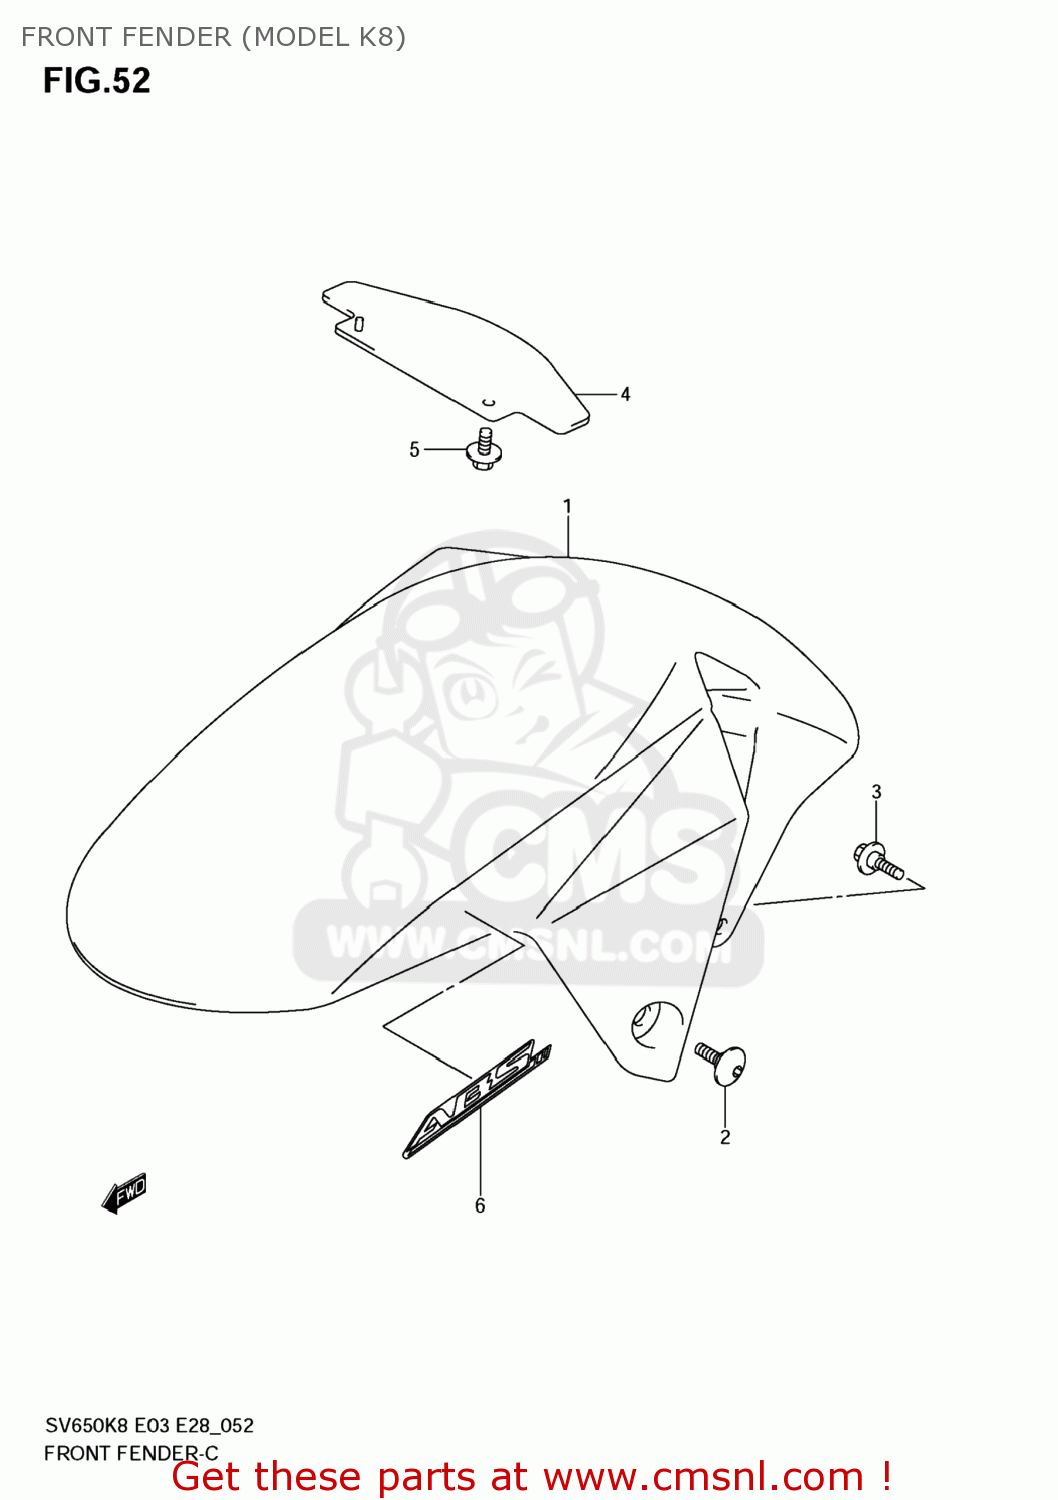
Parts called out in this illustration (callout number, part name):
1	FENDER,FR
2	SCREW(6X16)
3	SCREW(6X16)
4	FENDER,FR UPPER
5	BOLT(6X12)
6	EMBLEM,ABS
